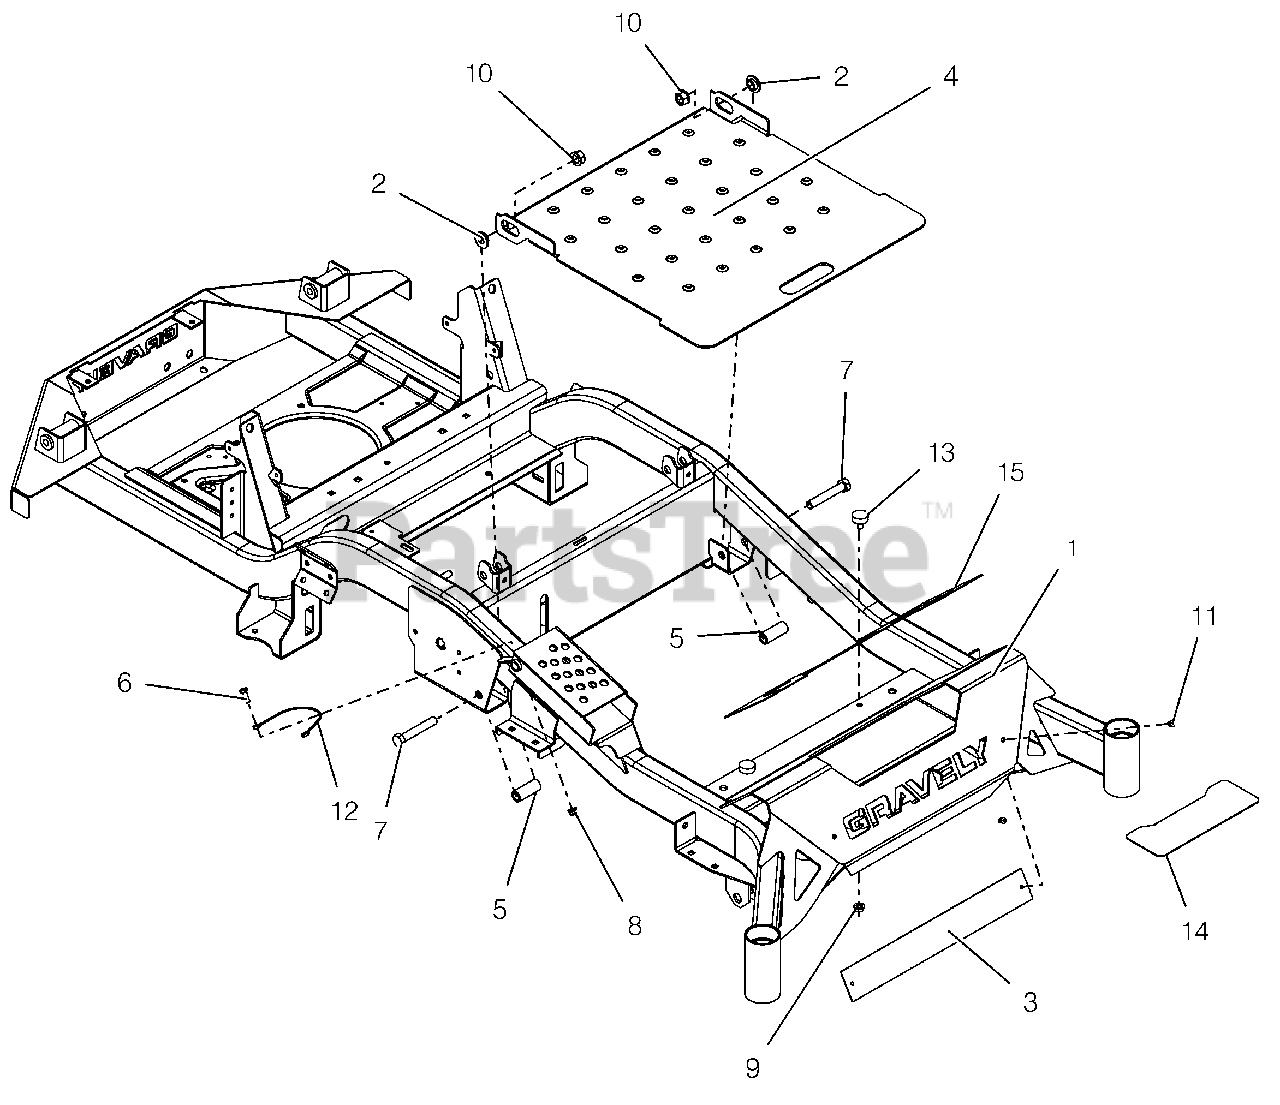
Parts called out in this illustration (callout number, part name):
1	HD 44-52 FRAME W/SAFETY DECALS
2	BSHG-FLG .515X.750X.310X1.120
3	PLATE, BACK FOOT-REST XL
4	PLATE, ACCESS
5	SPACER, .515X.75X1.83
6	@BLT-HEX .25-20X.75 GR5 YWZC
7	@BLT-HEX .50-13X3.00 GR5 YWZC
8	@NUT-LK-NYL-FLG .25-20 YWZC
9	@NUT-SPNLK-FLG .312-18 YWZC
10	@NUT-LK-TOP-FLG .50-13 YWZC
11	RIVET, .1875 AL/AL .126-.250
12	CABLE, 12.0 LANYARD, NYLON
13	BUMPER, RUBBER
14	GRIP, STEP
15	GRIP, FRONT
